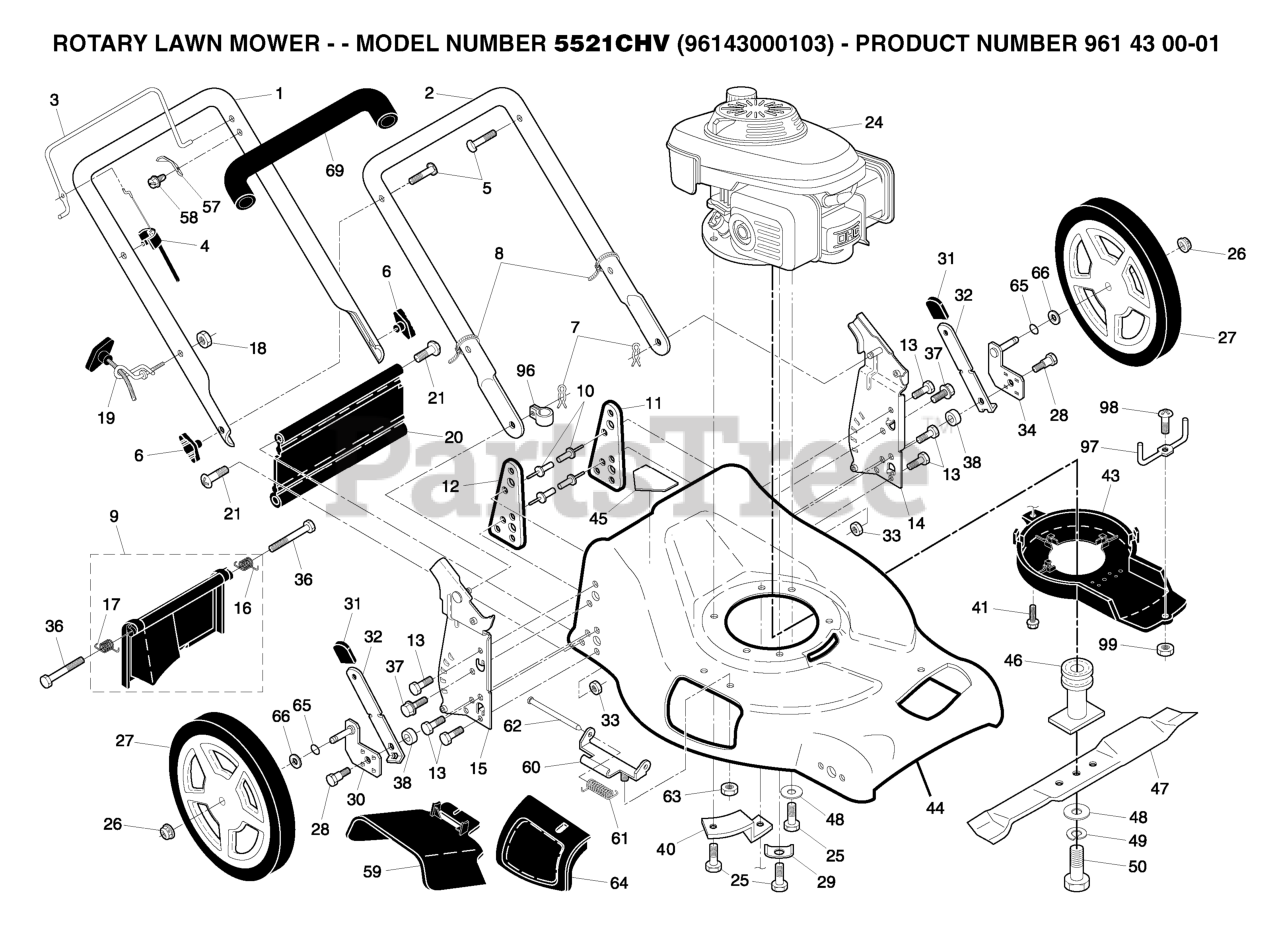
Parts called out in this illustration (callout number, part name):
1	RP HANDLE.ASM.UPPER.W/GRI
2	LOWER HANDLE
3	BAIL.DSTRT.FL.AW.CREAS.ORANGE
4	CABLE.ENGINE BRAKE.MZR
5	BOLT, HANDLE 5/16-18X1.75
6	HNDL.KNOB.GRAY
7	HAIRPIN COTTER
8	TIE GUIDE
9	KIT.DOOR.RR.ASM.21.FWGD
10	RIVET BLIND
11	SUPPORT BRACKET LH
12	SUPPORT BRACKET RH
13	SCREW 14-20 X 5/8
14	BRKT.ASM.HNDL.21FGD.EZ
15	BRKT.ASM.HNDL.21FGD
17	SPRING.REAR.DOOR.EZ.21
18	NUT
19	RB GUIDE.ROPE.STD.BLK.ZIN WSL
20	REAR SKIRT
21	HINGE SCREW
25	BOLT 3/8-16X1-1/8
26	NUT
27	WHEEL.12X1.75.5SPK.GRAY
28	SHOULDER BOLT
29	WASHER.ENGINE.BZP
30	ARM.ASM.AXLE.H/W,RR.BZ
31	SELECTOR KNOB
32	SPRING.SELECTOR.21.FWG.ZINC
33	NUT.71038.31-18.HEX.NYLOCK
34	ARM.ASM.AXLE.H/W.LR.BZ
37	SELF-TAPPING SCREW 5/16-18X3/4
38	WASHER.FLAT.34X1.38X22
40	BRACKET
41	SCREW.HEX.WSH
43	DEBRIS SHIELD
44	HOUSING.21.FGD.MC.ORANG.E/F.BK
45	DECAL HYT
46	RP ADAP.BLDE/PULL
47	BLADE.21.PUSH/RWGD/FWG
48	WASHER,HARDEN
49	LOCKWASHER
50	SCREW, HEX HD 3/8-24 X 1-3/8
57	BRACKET UPSTOP
59	DEFLECTOR.CLIPPIN.21.FGD
60	BRACKET.ASM.HINGE.21.FWGD.
61	SPRING.TORSION
62	ROD.HINGE.21
63	LOCKNUT.NYLOC.1/4-20
64	DOOR.MULCH.21.REAR.FWGD
65	O-RING..070X.487.NEOPRENE
66	WASHER.FLAT.1/2
69	GRIP.HANDLE.FOAM.WIDE.(1 SIDE)
96	CLIP.CABLE.BLK
97	KEEPER.BELT.FGD
98	SCREW.#8.MACH
99	NUT.HEX.#8
